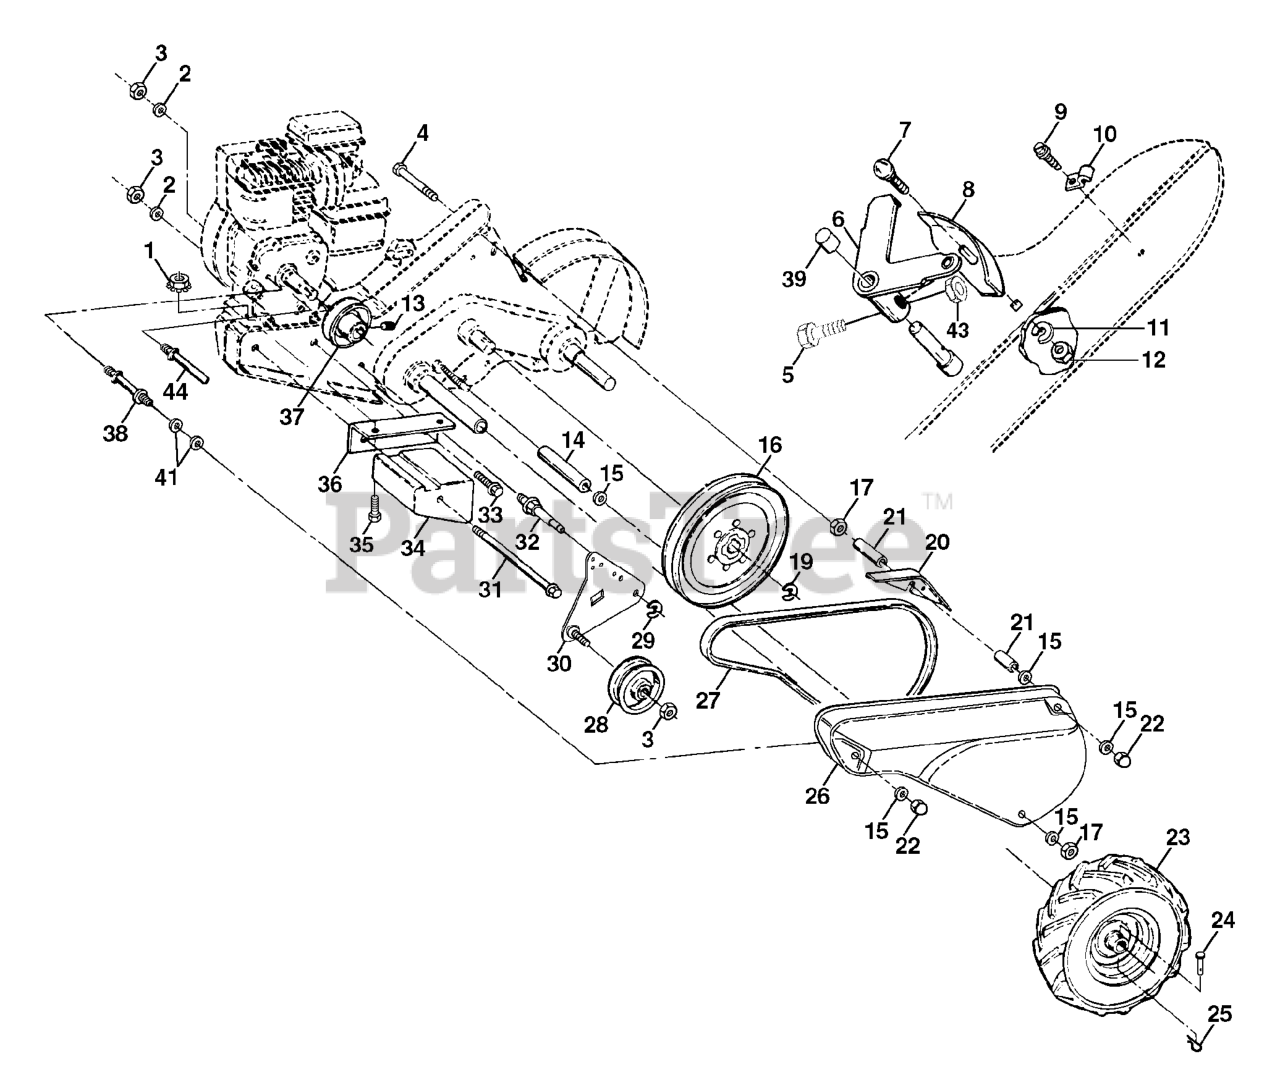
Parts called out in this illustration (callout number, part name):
1	NUT
2	WASHER, LOCK 3/8
3	NUT.HEX.3/8-16UNC
4	Bolt, Hex 5/16-18 x 4-1/4
5	SCREW, SHIFT LEVER
6	LEVER ASM CRT
8	PANEL.INDICATOR.SHIFT.BLACK
9	TAPPING SCREW
10	CONDUIT.CLIP.PLATED
11	LOCKWASHER
12	NUT
15	WASHER
16	SHEAVE, TRANSMISSION
17	NUT
19	RETAINING RING LT
21	SPACER, SPLIT
23	TIRE.16X4-8.CHEVRON.TILLER
23	RIM
23	VALVE STEM LT
24	RIVET,DRILLED
25	RETAINER M
26	BELT GUARD
27	V-BELT
28	PULLEY-IDLER TI
30	BRACKET.ASM.IDLER.BLACK
31	BOLT.FIN.HEX.3/8-16UNC
32	SHIFT ARM CRT
33	BOLT
34	COUNTERWEIGHT.LH.CRT
35	Bolt, Hex 5/16-18 x 1 1/2
36	BRACKET LH CRT
37	RP.ENGINE PULLEY
38	BELT GUARD STUD
39	CAP.PLUNGER.BLACK
44	KEEPER.BELT.ENGINE
